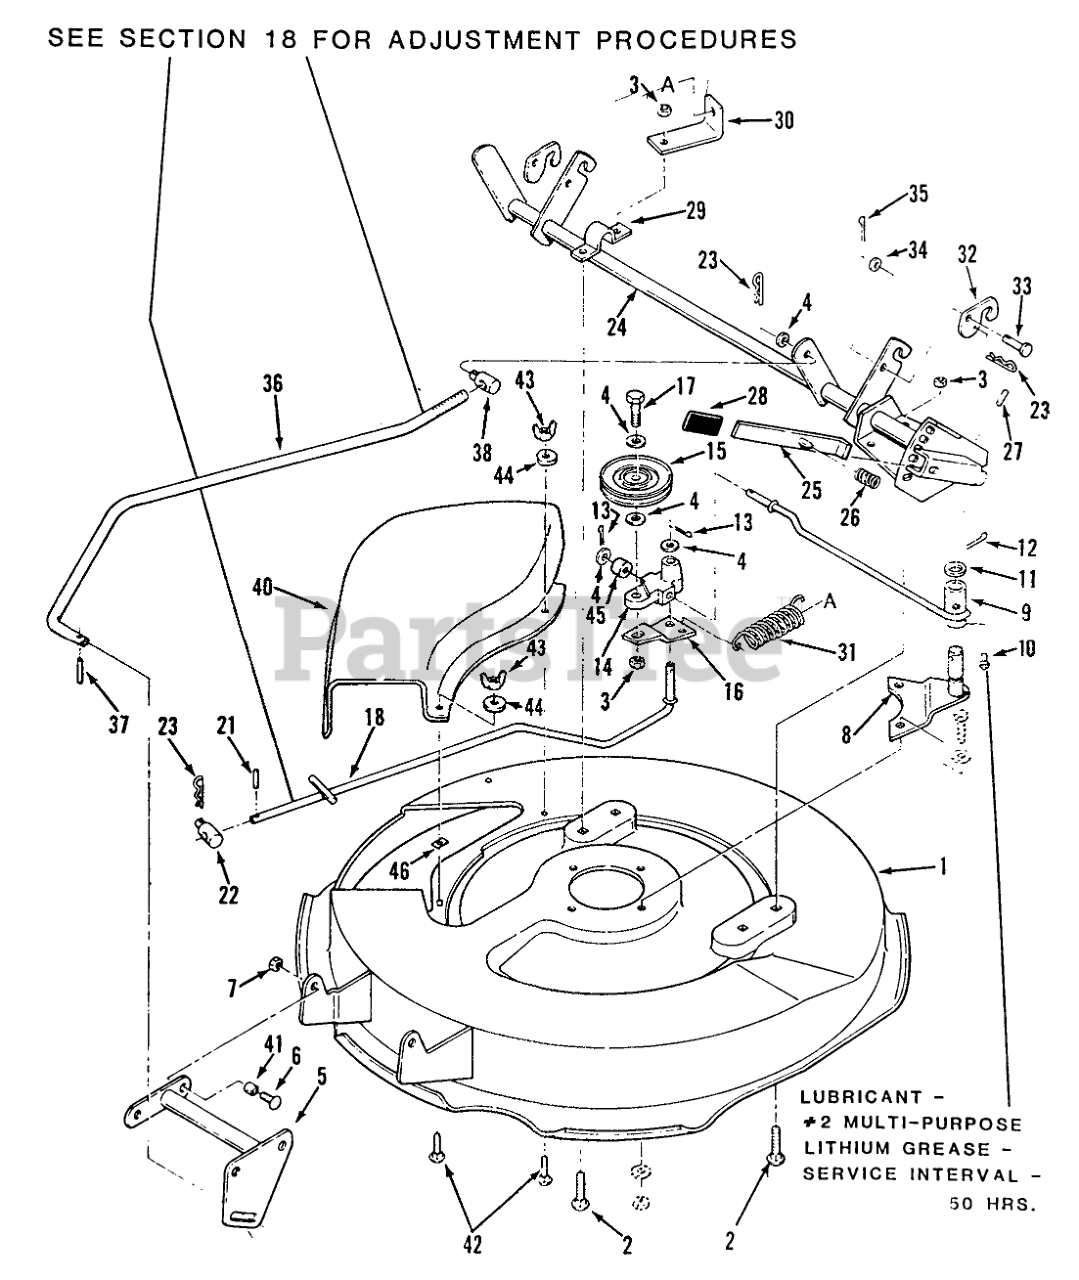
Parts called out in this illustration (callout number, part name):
1	ASM-DECK (30") R
2	Bolt
3	NUT
4	Washer
5	ASM-FRONT LIFT R
6	Bolt-Carriage
7	LOCKNUT-FLANGE
8	ASM-PIVOT, IDLER
9	Idler Arm
10	Zerk
11	WASHER
12	Cotter Pin
13	Pop Rivet
14	BLOCK IDLER
15	PULLEY-IDLER V
16	ANCHOR-SPRING
17	Bolt
18	ASS'Y-IDLER ROD
21	Pin-Roll
22	TRUNNION-LIFT
23	Hairpin Cotter
24	Height Adjust Assy
25	LEVER ASSY
26	SPRING-COMPRESSION
27	PIN-SPIROL
30	ANCHOR-SPRING B
31	SPRING-EXTENSION
32	Latch
34	Washer
35	Cotter Pin
36	ASS'Y-HEIGHT ADJ R
37	SPIROL PIN
38	STUD-TRUNION
40	Deflector
41	SPACER
42	Bolt-Carriage
43	Nut-Wing
44	WASHER
45	SPACER
46	SPEED NUT 1/4-20
